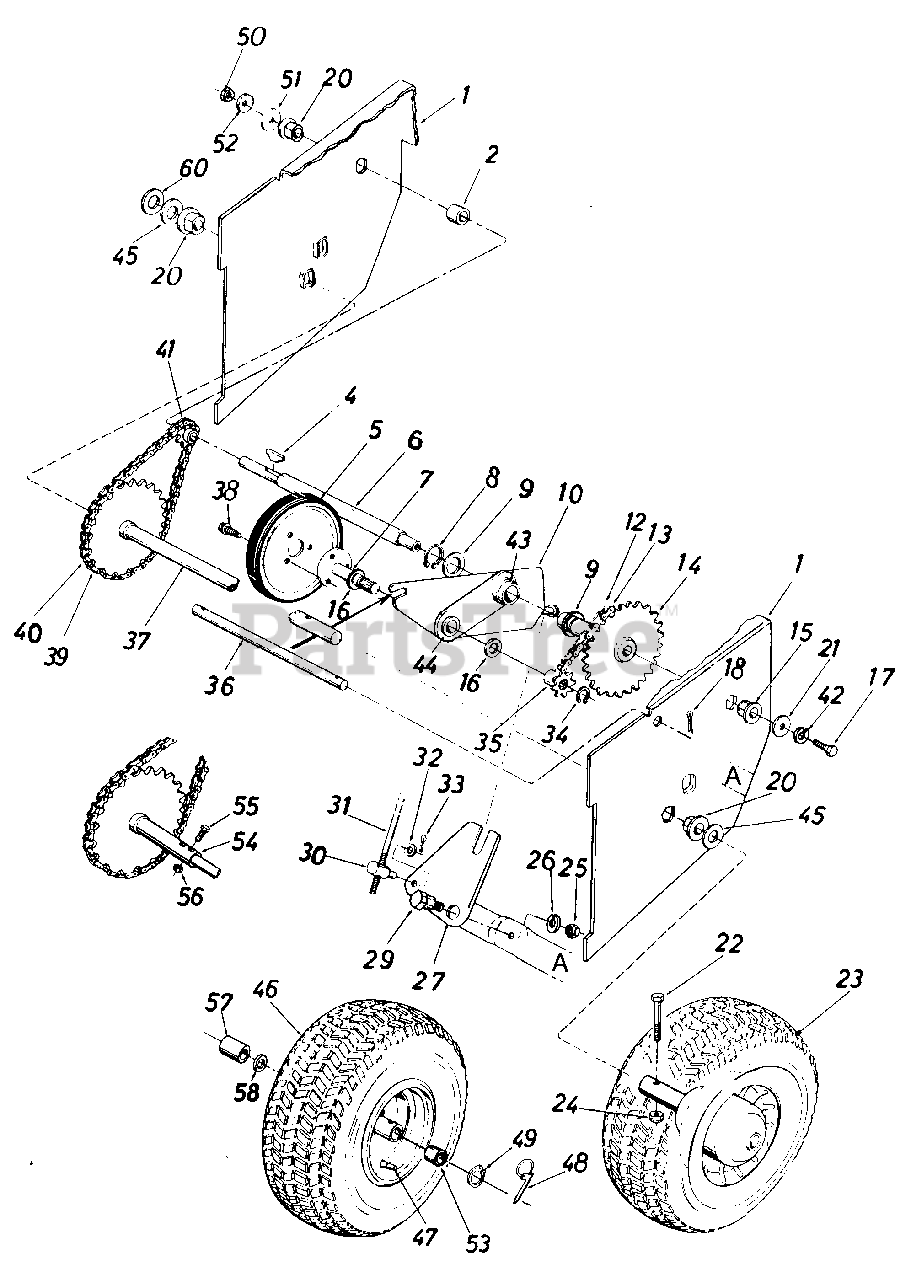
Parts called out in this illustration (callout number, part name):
1	Frame Ass'y.
2	Spacer .50" I.D. x .75" O.D. x .78" Lg.
4	#4 Hi-Pro Key 3/32 x 5/8" Dia.
5	Friction Wheel Ass'y.
6	Hex Shaft
7	Friction Wheel Mounting Plate Ass'y.
8	Snap Ring 1.00" Dia. Shaft
9	Fl-Wash. 1.00" x 1.63" O.D. x .03
10	Sliding Bracket Ass'y.
12	#41 Chain 1/2" Pitch x 35 Links
13	Master Link for #41 Chain
14	32 Teeth Sprocket Ass'y.
15	Hex Flange Brg. .630" I.D.
16	Fl-Wash. .62" I.D. x 1.00" O.D. x .06
17	Hex Lock Bolt 5/16-18 x .62" Lg.
18	Cotter Pin 3/32" Dia. x .75" Lg..
20	Flange Brg. w/Flats .755" 1. D.
21	Fl-Wash. .34" I.D. x 1.12" O.D. x .125
22	Hex Bolt 5/16-24 x 1.50" Lg. (420)
24	Hex Ins. Jam L-Nut 5/16-24 Thd. (420)
25	Hex Jam Nut 3/8-16 Thd.
26	L-Wash. 3/8" I.D.
27	Shifting Linkage Bracket
29	Shld. Bolt .625" Dia. x .170" Lg.
30	Adjustment Ferrule
31	Shifting Rod 5/16" Dia. x 32.50" Lg.
32	Fl-Wash. .34" I.D. x .64" O.D. x .06
33	Cotter Pin 3/32" Dia. x .75" Lg.
34	Snap Ring .562" Dia. Shaft
35	Sprocket 7 Teeth x .50" Pitch
36	Shaft .50" Dia. x 9.50" Lg.
37	28 Teeth Wheel Axle Ass'y. (420)
38	Hex Wash. Hd. Self-Tap Scr. 5/16-24 x .50" Lg.
39	#41 Chain 1/2" Pitch x 43 Links (420)
40	Master Link for #41 Chain (420)
41	8 Teeth Center Sprocket
42	L-Wash. 5/16" I.D.
43	Bearing
44	Bronze Bearing
45	Fl-Wash. .76" I.D. x 1.49 O.D.
47	Air Valve
48	Klick Pin (524)
49	Snap Ring .75 Dia. (524)
50	Hex Ins. L-Nut 1/2-20 Thd.
51	Fl-Wash. .53 I.D. x 1.25 O.D. x .10
52	Bell-Wash. .50 I.D. x 1.0 O.D. x .075
53	Sleeve Brg. (524)
